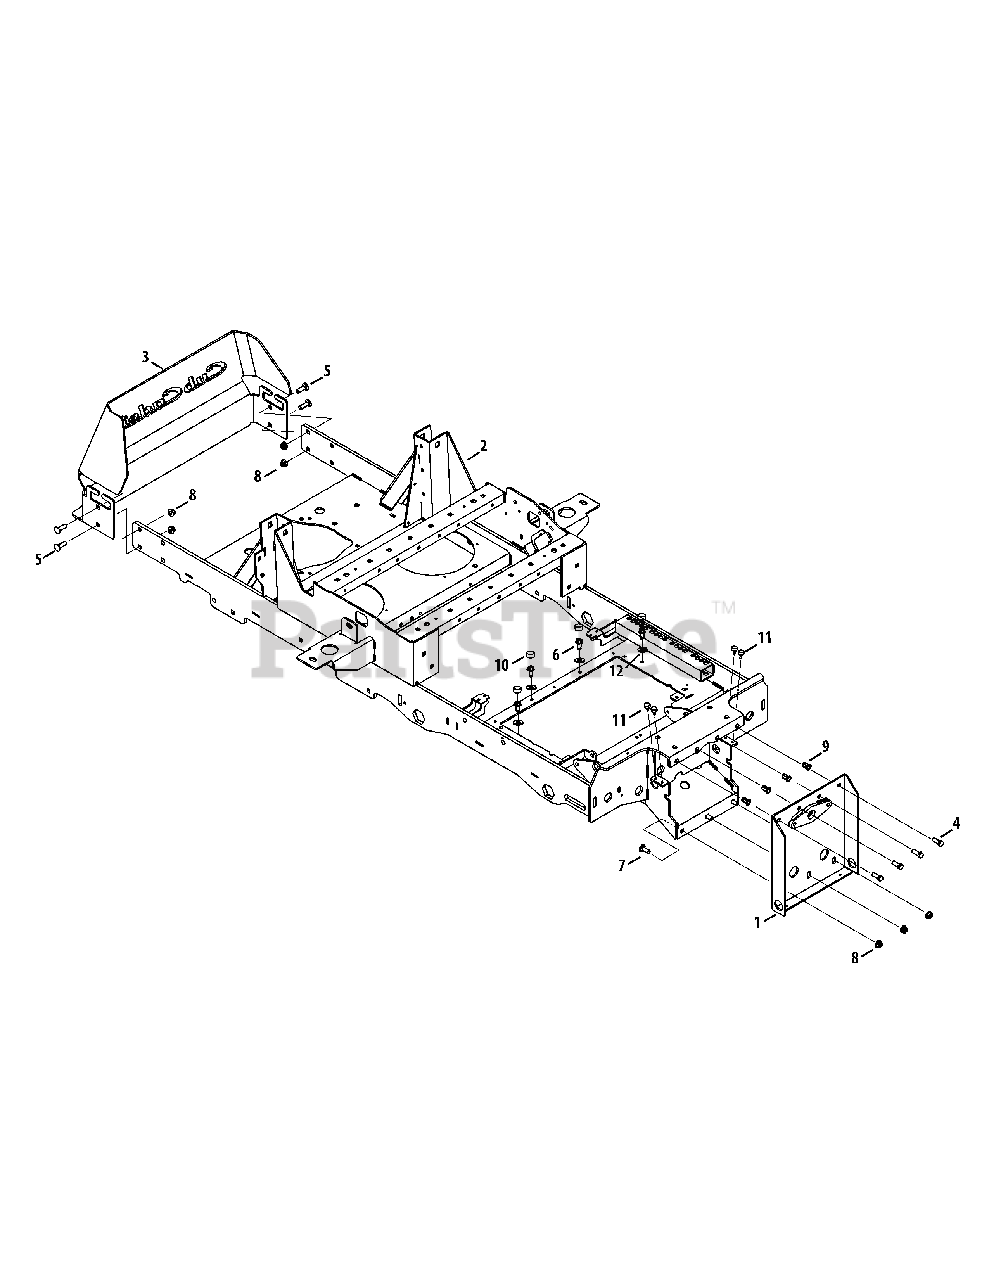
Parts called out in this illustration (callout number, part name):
1	Front Axle Bracket Assembly
2	Frame Assembly
4	Hex Cap Screw, 3/8-16 x 1.00
5	Carriage Bolt, 3/8-16 x 1.25
6	Screw, 3/8-16 x .750
7	Carriage Bolt, 3/8-16 x 1.00
8	Nylock Nut, 3/8-16
9	Rivet Nut, 3/8-16
10	Slide Cap
11	Bumper, .62 Dia. x .3
12	Washer, .406 x 1.00 x .105
